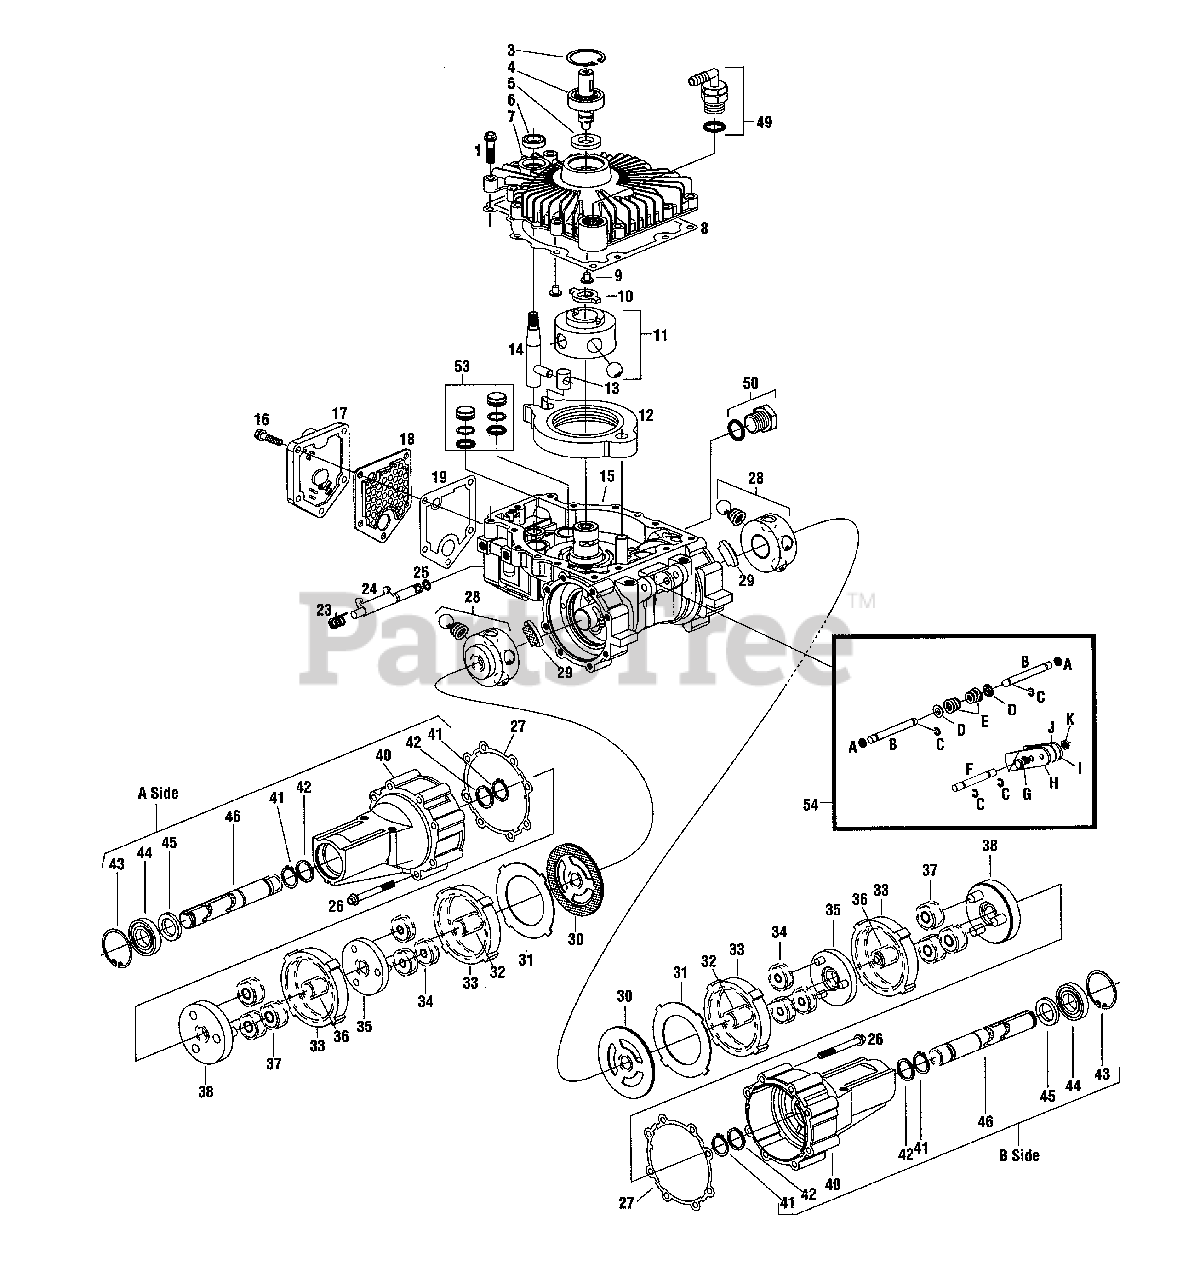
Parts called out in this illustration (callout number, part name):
1	Self Tapping Screw, 1/4-20
3	Ring, Retaining, Internal
4	Shaft, Input (S/A)
5	Seal Input Shaft
6	Seal, Control Shaft
7	Cover
8	Gasket, Cover
9	Button
10	Drive
11	Pump Rotor/Ball/Pin (S/A)
12	Cam Ring
13	Insert
14	Control Shaft, External Thread
15	Housing (S/A)
16	Screw, 1/4-20 Hex Range
17	Filter Base "L"
18	Filter
19	Gasket
23	Spring, Dump Valve
24	Bracket, Dump Valve
25	Seal, O-ring
26	Screw, 5/16 Hex Range
27	Gasket, Axle Housing
28	15T Motor Rotor/Ball (S/A)
29	Pad, Friction (S/A)
30	Reaction, Plate
31	Plate, Backup
32	15T Sun Gear, First
33	Gear, Ring 57T
34	21T Planet Gear (S/A) First
35	15T Primary Carrier (S/A)
36	15T Sun Gear, Second (Steel)
37	21T Pint. Gear (S/A) Second (Steel)
38	Secondary Carrier (S/A)
40	Axle Housing (S/A) A-Side & B-Side
41	Ring, Retaining, External
42	Thrust Washer
43	Ring, Retaining, Internal
44	Bearing, Ball
45	Seal, Radial Lip
46	Shaft, Axle-A-Side
49	90° Fitting/O-ring (S/A)
50	Plug/O-ring (S/A)
53	Piston, (S/A)
54	Brake Lever Parts
A	Quad Seal
B	Rod, Push
C	E-Ring
D	Spring Base (S/A)
E	Spring Conical
F	Shaft, Brake
G	Screw, Cap, Hex
H	Lever, Brace, R.H.
I	Lever, Brake, L.H.
K	Nut, Hex, Lock
